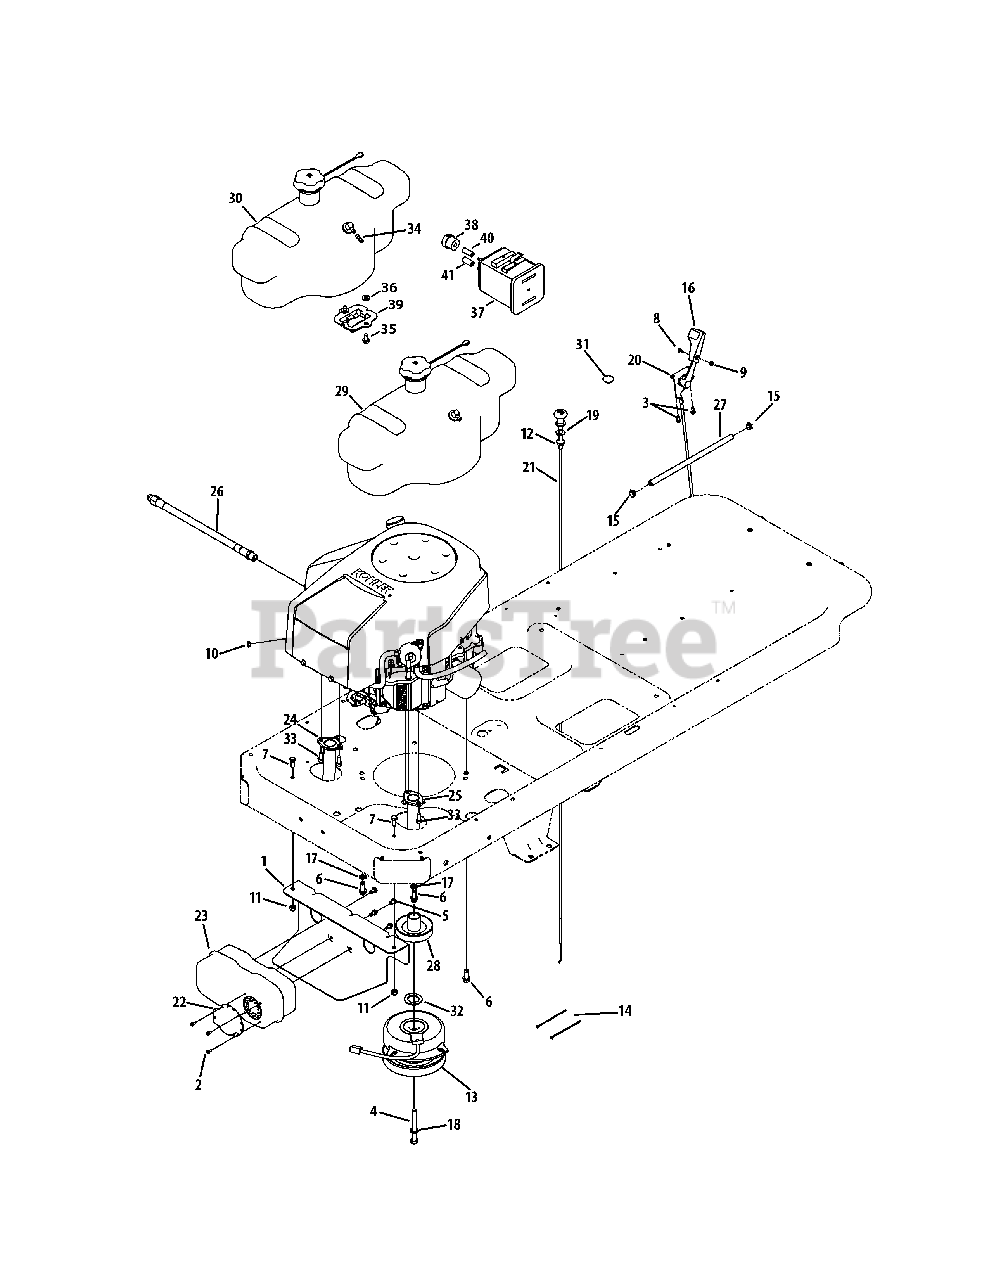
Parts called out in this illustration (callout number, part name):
1	Muffler Mount Bracket
2	Hex Washer Screw, #8-18 x .500
3	Screw, 1/4-14 x .625
4	Hex Lock Screw, 7/16-20 x 3.50
5	Hex Washer Screw, 1/4-20 x .500
6	Hex Washer Screw, 3/8-16 x 1.000
7	Hex Washer Screw, 5/16-18 x .75
8	Machine Screw, #8-32 x .375
9	Hex Nut, #8-32
10	Sems Nut, 1/4-20
11	Flange Lock Nut, 5/16-18
12	Flange Lock Nut, 3/8-16
13	Electric PTO Clutch
14	Cable Tie
15	Hose Clamp
16	Throttle Control Knob
17	Lock Washer, 3/8
18	Lock Washer, 7/16
19	Flat Washer, .406 x .875 x .059
20	Throttle/Choke Control Cable
21	Choke Cable
22	Muffler Deflector
23	Dual Inlet Muffler
24	Exhaust Pipe, LH
25	Exhaust Pipe, RH
26	Oil Drain Hose
28	Engine Pulley
29	Fuel Tank Assembly
29	Fuel Tank Bushing
29	Fuel Pick-Up Fitting
29	Fuel Tank
29	Fuel Cap
30	Fuel Tank Assembly
31	Choke Plug
32	Flat Washer, 1.03 x 1.620 x .095
33	Screw, 5/16-18 x .750
34	Hose Vent, 3/16 EPA
35	Screw 5/16-18 x .875
36	Washer, Flat, .344 x .750 x .120
37	Canister, Carbon, 5 Gallon
38	Filter, Vent, Canister
39	Bracket., Adapter, Canister
40	Hose, Fuel, Low Perm., White
41	Hose, Fuel, Low Perm., Yellow
